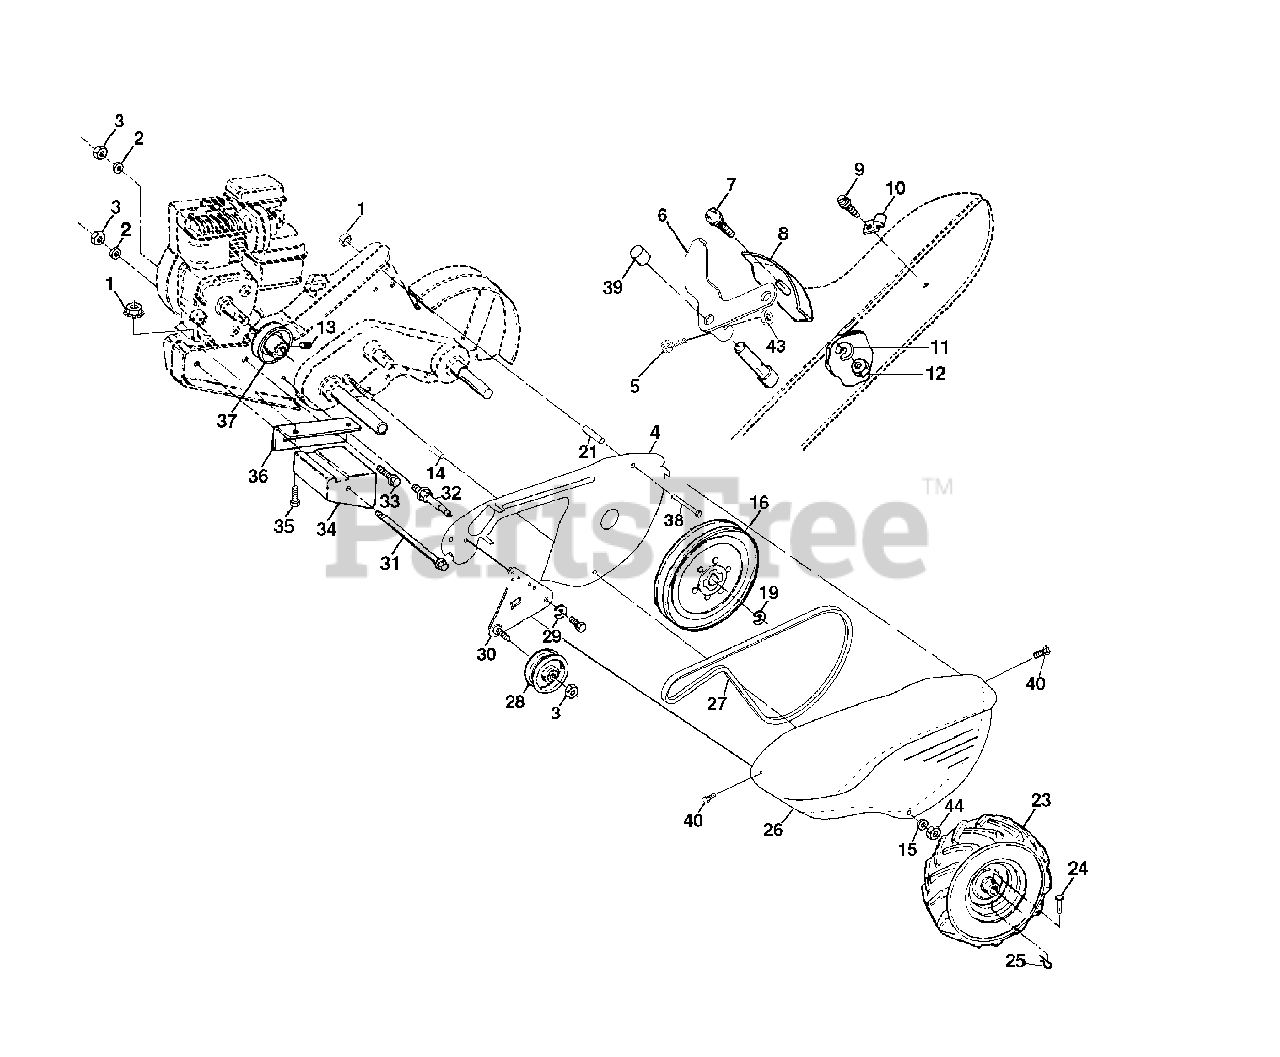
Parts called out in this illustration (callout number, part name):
1	Nut, Keps 5/16-18
2	Washer, Lock 3/8
3	Nut, Hex 3/8-16
4	Shield Inner Belt Guard
5	Screw Shift Lever
6	Lever, Shift
7	Bolt, Carriage 1/4-20 x 1/2 Gr. 5
8	Plate, Shift Indicator
9	Screw, Hex, Washer Head, Slotted #10-24 x 1/2
10	Clip
11	Washer, Lock 1/4
12	Nut, Hex 1/4-20
13	Screw, Set, Hex 5/16-18 x 3/8
14	Spacer, Split 0.327 x 0.42 x 1.220
15	Washer 11/32 x 11/16 x 16 Ga.
16	Sheave, Transmission
19	Ring, Retainer
21	Spacer, Split 0.327 x 0.42 x 2.09
22	Bolt Fin Hex 5/16-24 x 1/2
23	Tire
23	Rim
23	Tire Valve
24	Rivet, Drilled
25	Clip, Hairpin
26	Guard, Belt
27	Belt, V
28	Pulley, Idler
29	Ring, Klip
30	Bracket, Idler
31	Bolt, Hex 5/16-16 x 12
32	Shaft, Idler Arm
33	Bolt, Hex 3/8-16 x 1
34	Counterweight, L. H.
35	Bolt, Hex 5/16-18 x 1-1/2
36	Bracket, Reinforcement, L. H.
37	Sheave, Engine
38	Bolt Fin Hex 5/16-18 x 2-3/4
39	Cap, Plunger Blk
40	Screw Hex Wsh. SLT #10-24 x .50
43	Nut Lock #10-24
44	Nut Lock Hx W/Ins 5/16-18
